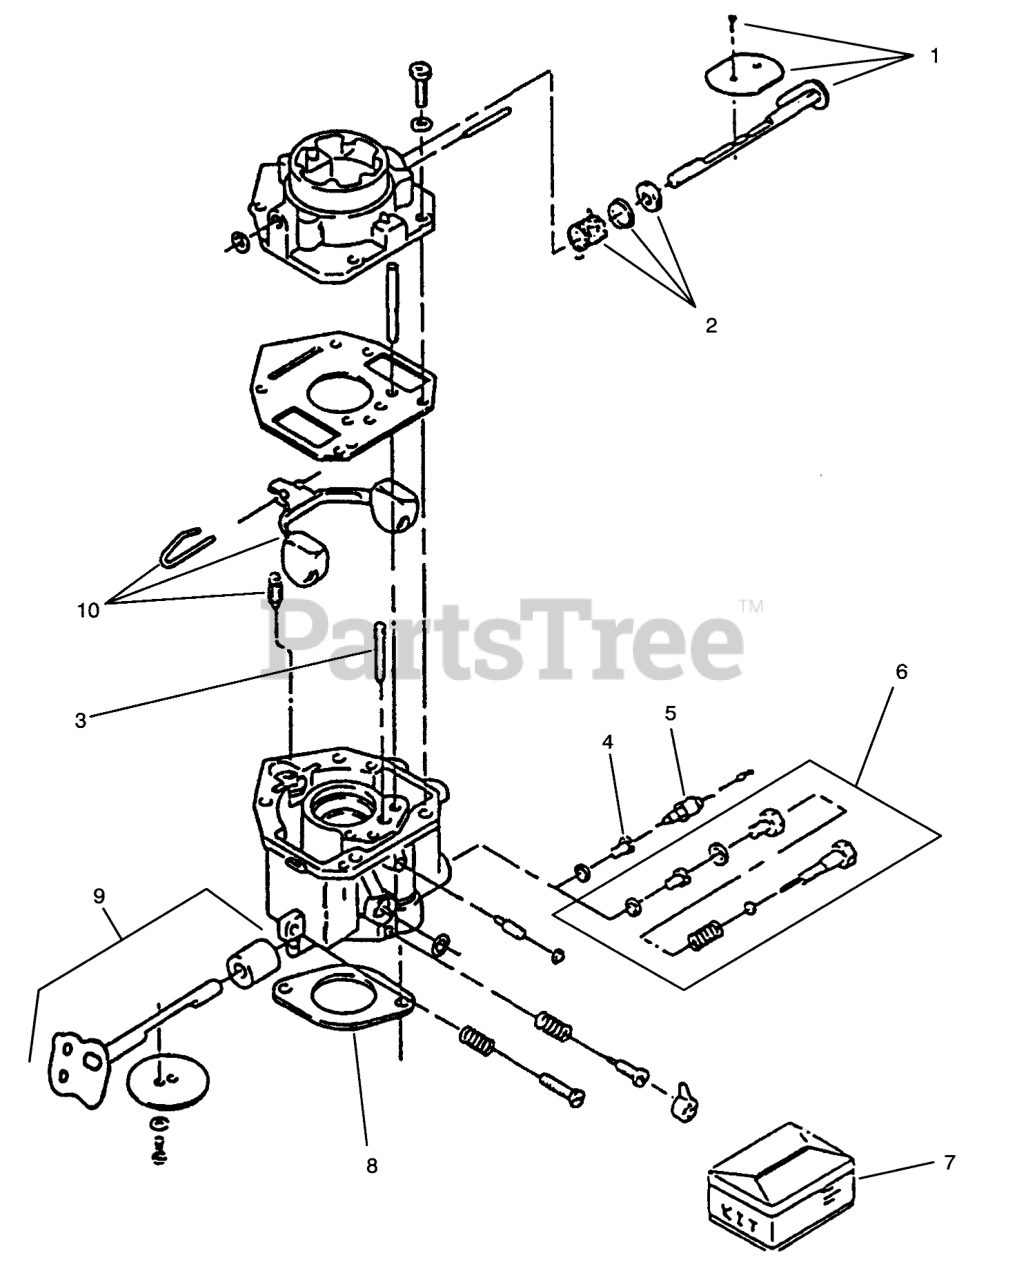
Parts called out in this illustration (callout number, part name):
1	Choke Shaft Kit
2	CHOKE-LEVER KIT
3	Idle Jet
4	POWER JET
5	Solenoid
6	FIXED-JET PKG
7	Carburetor Repair Kit
8	Gasket
9	SHAFT-THROTTLE KIT
10	Kit-Float (Includes Float Pin)
